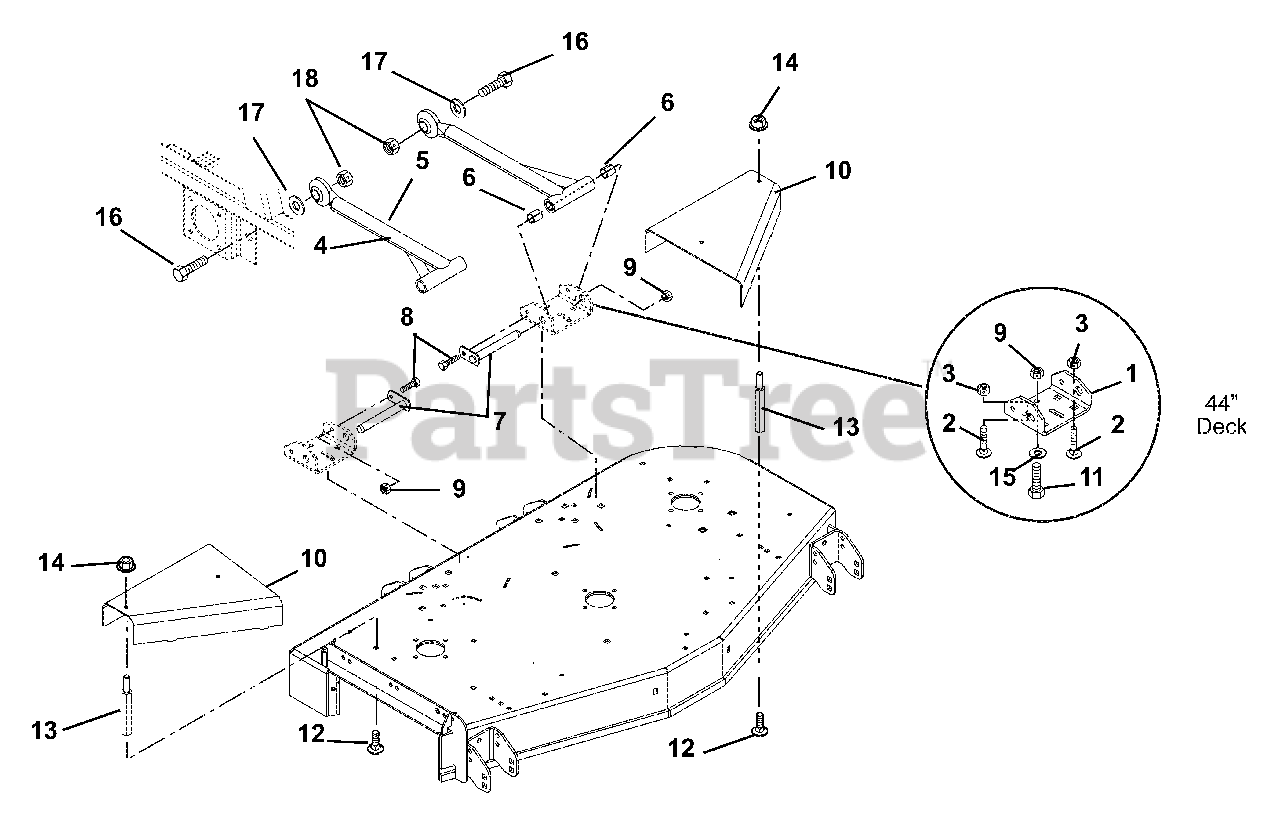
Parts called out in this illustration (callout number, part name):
1	BRACKET, MOWER MOUNT (REAR)
2	@BLT-RDHDSQNK .50-13X.75 G5YZ
3	NUT-LK-CTR-JAM .50-13 YWZC(ND)
4	ASSY, MOWER MOUNTING
5	MOWER MTG ARM - BLACK
6	BRG, .750 X .875 X 1.000
7	WELDMENT, MOWER MTG. PIN
8	@BLT-HEX .38-16X.75 GR5 YWZC
9	@NUT-LK-TOP-FLG .38-16 YWZC
10	GUARD, PULLEY-44,48 (RED)
11	@BLT-RDHDSQNK .38-16X.75 G5YZ
12	BLT,RDHDSQNK .31-18X.75 LOCTIT
13	STANDOFF, 2.75 X 5/16-18
14	@NUT-LK-TOP-FLG .31-18 YWZC
15	@WSHR-FL-STL.406X.812X.065 YWZ
16	BLT-HEX .875-9X2.75 GR5 YWZC
17	WSHR-FL-STL .890X1.500X.1196YZ
18	NUT-LK-CTR .875-9 YWZC
